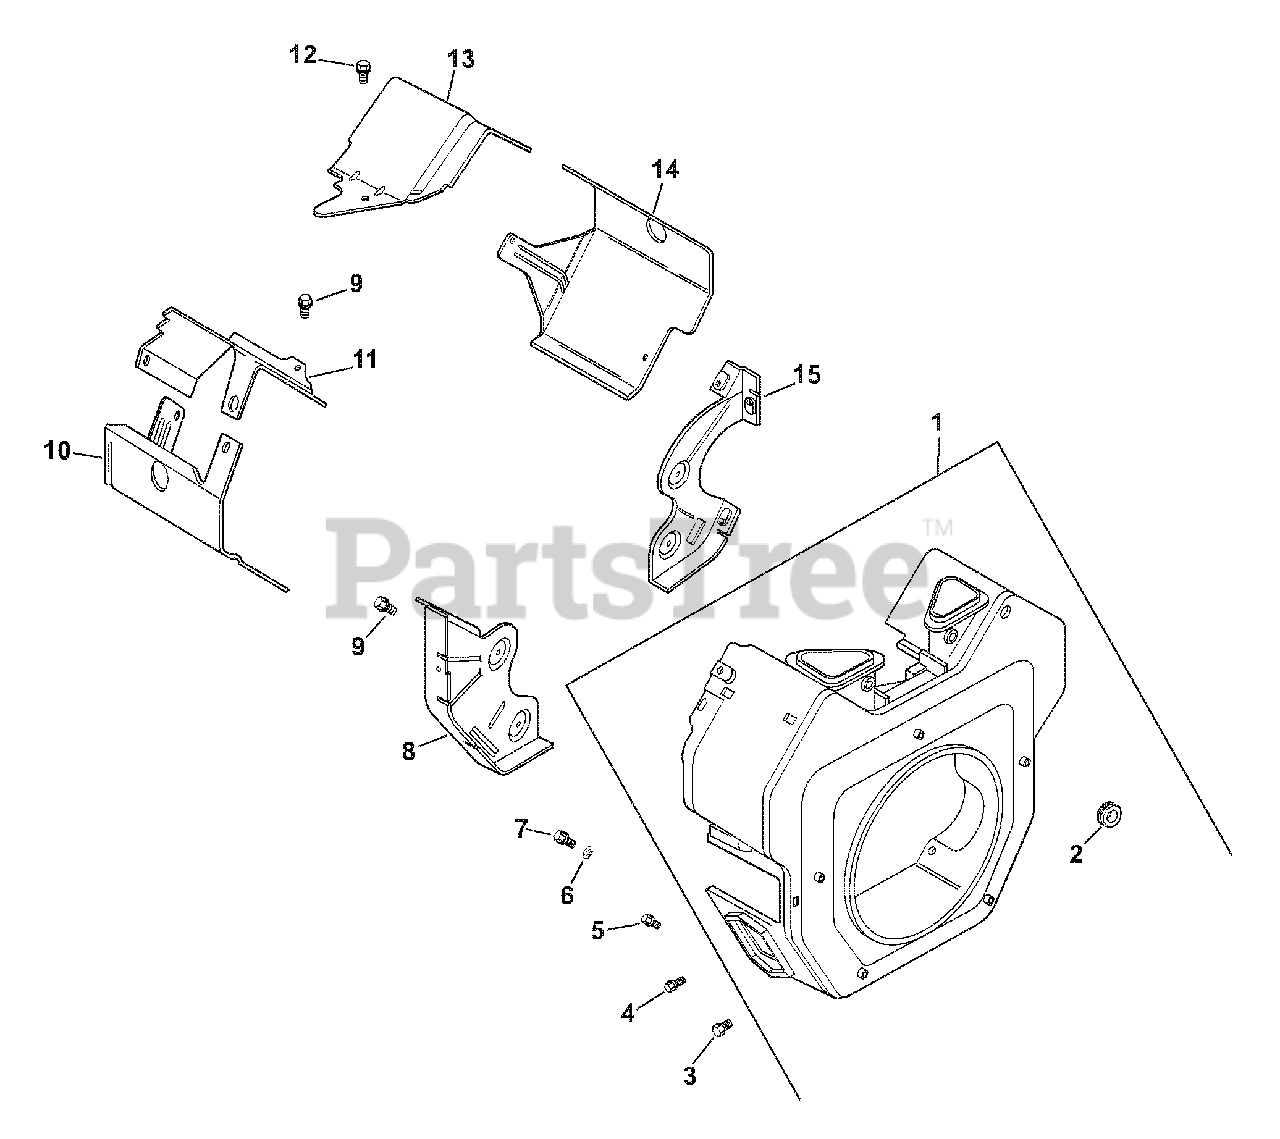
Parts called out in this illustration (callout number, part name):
1	Housing, blower
3	Screw, hex. flange M5x0.8x16
4	Screw, hex. flange M5x0.8x16
5	Screw, hex. flange M5x0.8x20
6	Washer, plain
7	Screw, hex. flange M5x0.8x25
8	Plate, backing - #2 side
9	Screw, hex. flange M6x1.0x16
10	Baffle, cylinder barrel - #2 side
11	Baffle, valley - #2 side
12	Screw, hex. flange M5x0.8x10
13	Baffle, valley - #1 side
14	Baffle, cylinder barrel - #1 side
15	Plate, backing - #1 side
